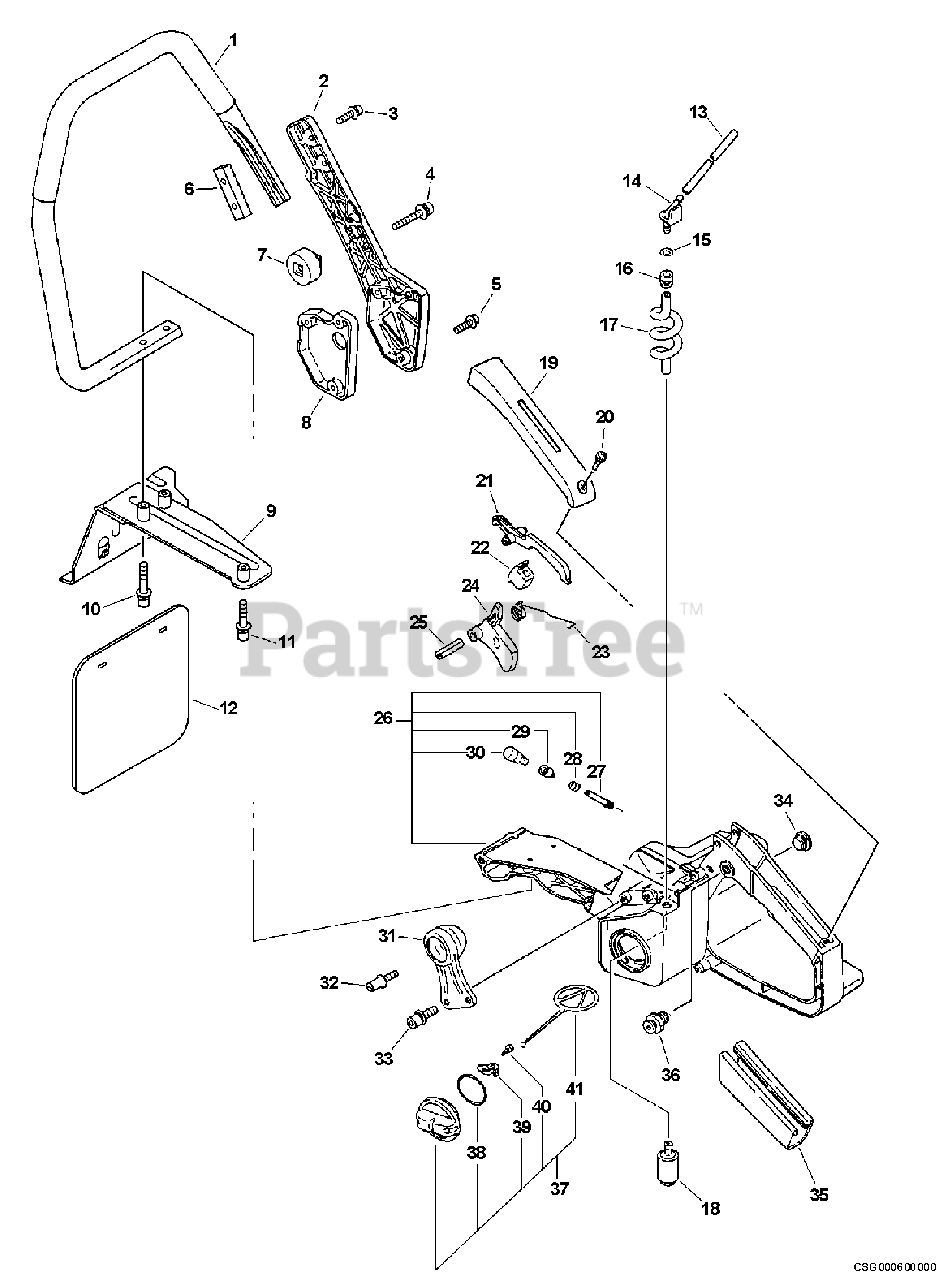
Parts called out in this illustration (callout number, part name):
1	HANDLE, FRONT
2	BRACKET, GRAY HANDLE
3	SCREW 5×20
4	SCREW 5×30
5	SCREW 5×35
8	SPACER
9	FIXTURE,HANDLE
10	BOLT M5×35
11	BOLT 5×30
12	SHIELD
13	PIPE, FUEL - 3×6×100
14	CONNECTOR, PIPE
15	CLIP Ø6.5 MM
16	GROMMET
17	PIPE, FUEL
18	FILTER, FUEL
19	COVER, HANDLE
20	SCREW 4×14
21	LEVER, THROTTLE LOCKOUT
22	CUSHION, THROTTLE
23	SPRING, THROTTLE RETURN
24	TRIGGER, THROTTLE - ORANGE
25	PIN, SPRING Ø5×25 MM
26	HANDLE, REAR
27	PIPE, VENT
29	HOLDER, VENT
30	VENT ASSY
33	BOLT 5×14
34	GROMMET, PLUG
35	GRIP, HANDLE
36	LOCK, THROTTLE TRIGGER
37	CAP ASSY, FUEL
38	O-RING 29
39	RETAINER, CONNECTOR
40	SCREW, TAPPING 3×8
41	CONNECTOR, CAP L= 60 MM
